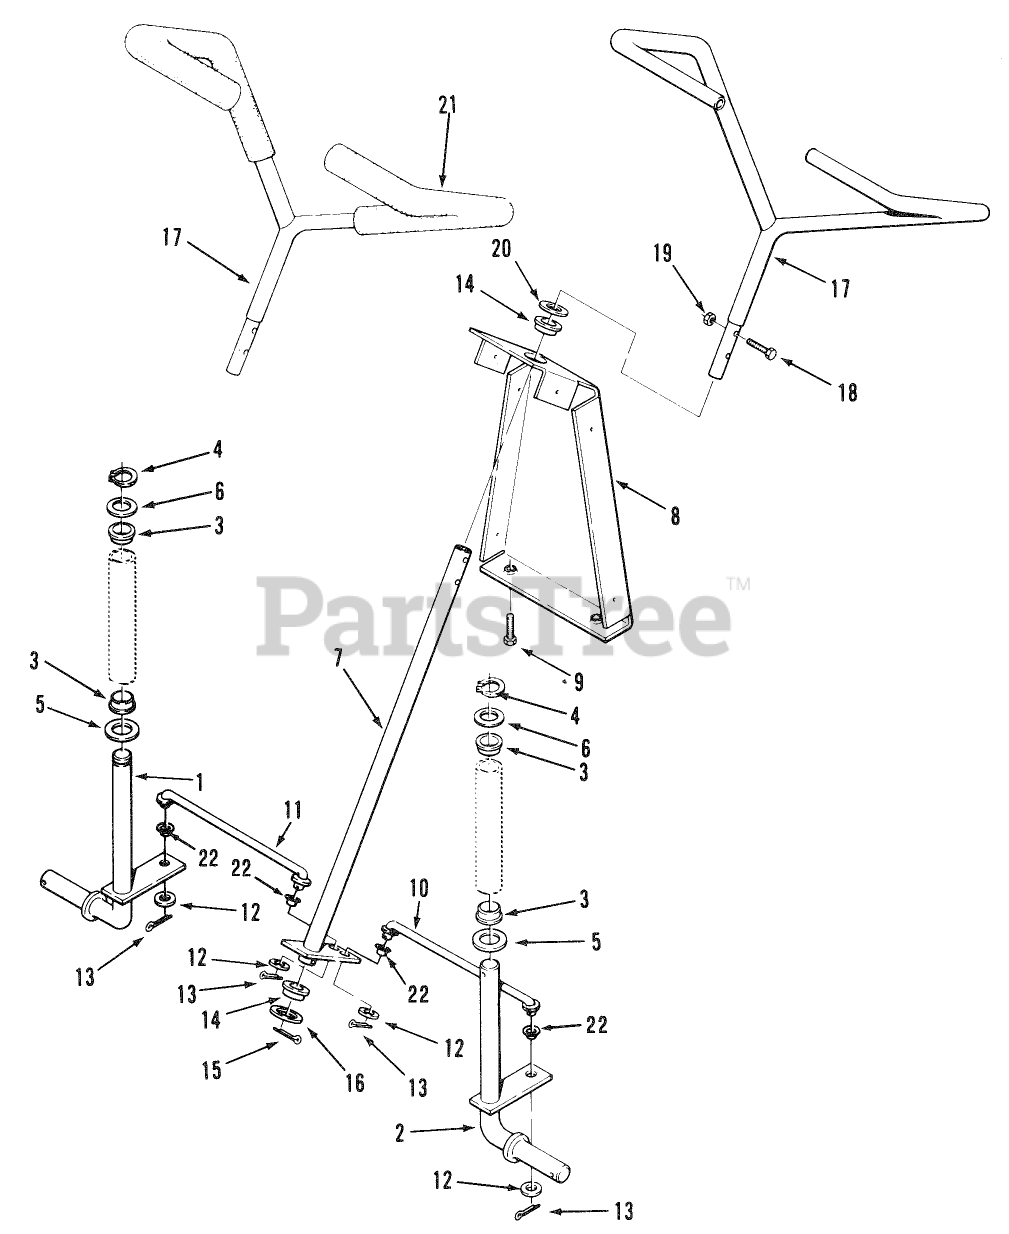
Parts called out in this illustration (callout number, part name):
1	ASS'Y-SPINDLE RH. *R
3	BUSHING
6	WASHER
9	Screw
14	BEARING
16	WASHER-FLAT
22	BEARING
